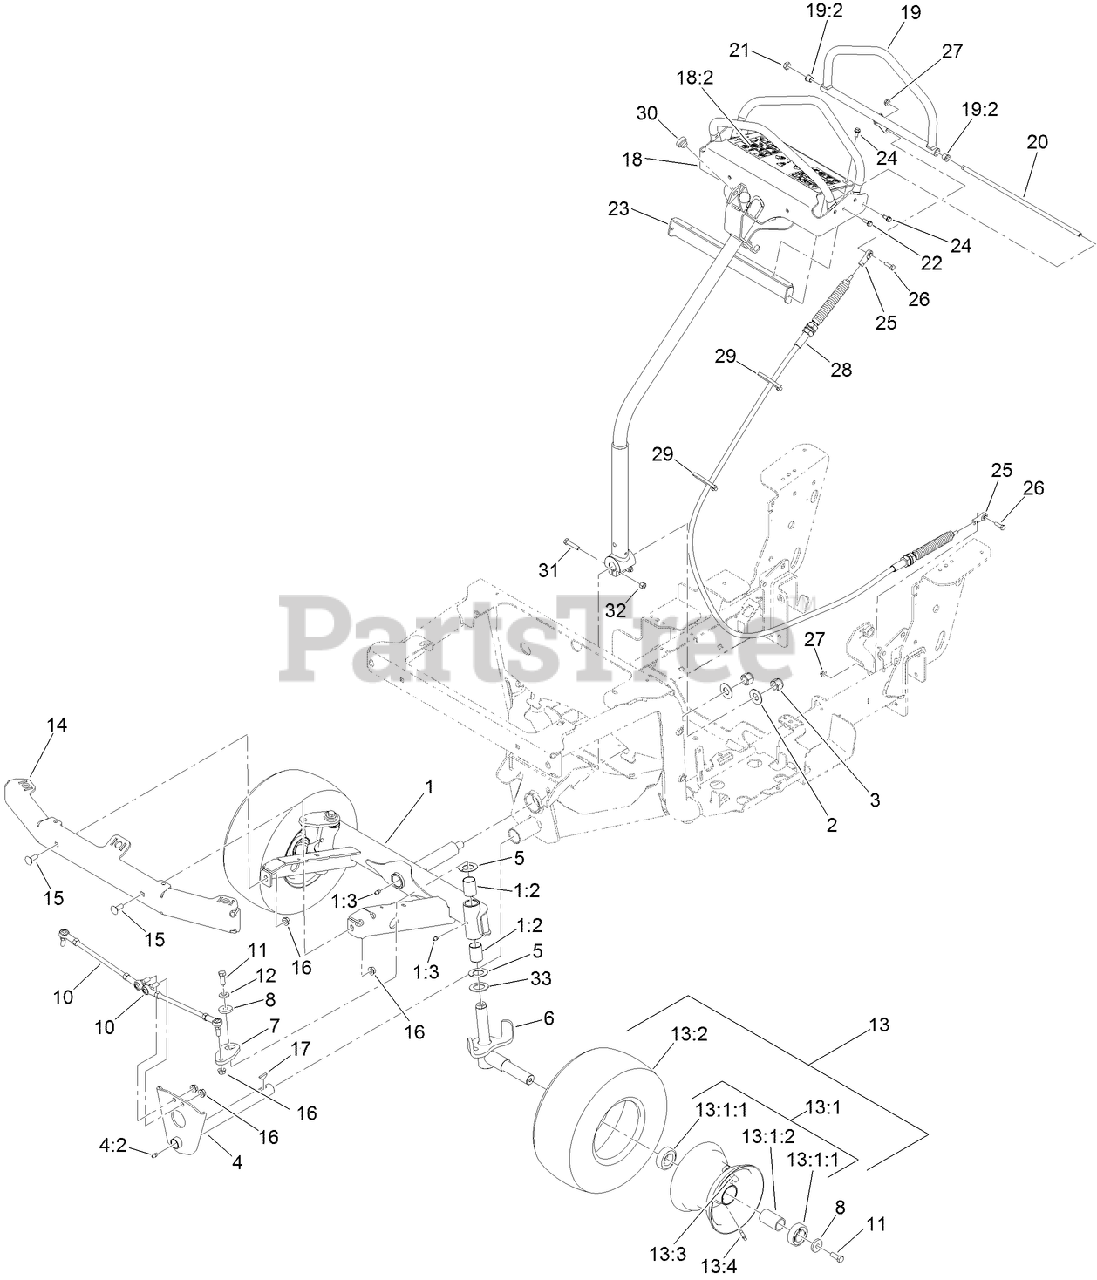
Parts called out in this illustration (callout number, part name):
1	FRONT AXLE ASM
1:2	BEARING-SLEEVE
1:3	ZERK-GREASE
2	WASHER-FLAT
3	NUT-HEX, NI
4	STEERING SHAFT ASM
4:2	ZERK-GREASE
5	WASHER-THRUST
6	FRONT AXLE ASM
7	ARM-STEERING
8	WASHER
10	STEERING LINKAGE ASM
11	SCREW-HH
12	WASHER-BELLEVILLE
13	WHEEL AND TIRE ASM
13:1	WHEEL ASM
13:1:1	BEARING-BALL
13:1:2	SPACER
13:4	FITTING-GREASE
14	BUMPER-FRONT
15	SCREW-CARR
16	NUT-HF
17	KEY-WOODRUFF
18	MOTION HANDLE ASM
18:2	DECAL-WARNING
19	MOTION HANDLE ASM
19:2	BEARING
20	SHAFT-PIVOT, SPEED CONTROL
21	SPACER-SHAFT, DRIVE LEVER
22	SCREW-HHF
23	PANEL-REAR, STEERING
24	SCREW-HWH
25	ROD END-BALL JOINT
26	SCREW-HH
27	NUT-HF
28	CABLE-MOTION
29	TIE-CABLE
30	BUMPER-RUBBER
31	SCREW-HH
32	NUT-HEX
33	SPACER-RELIEF
